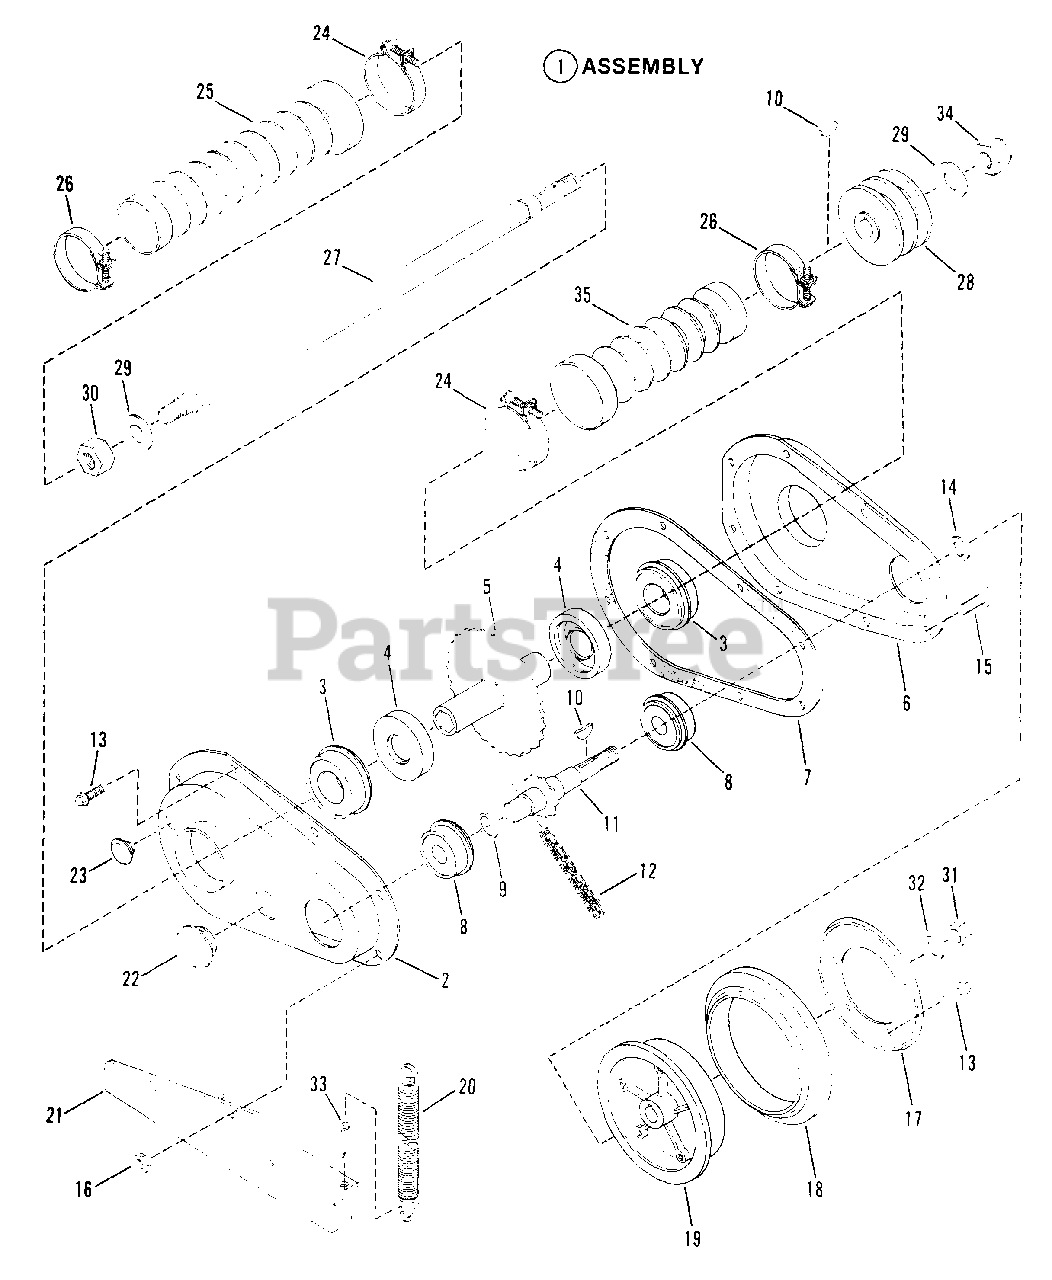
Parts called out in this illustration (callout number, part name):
1	ASSEMBLY, Chain Case
2	COVER, Chain Case, R.H.
3	BEARING, 3/4"
5	HUB & SPROCKET
6	COVER, Chain Case, L.H.
7	GASKET, Chain Case
8	BEARING
9	O-RING, 15/32
10	KEY, Woodruff, 3/32 x 1-1/2"
11	DRIVE SPROCKET
12	CHAIN
13	SCREW, #10-24 x 1/2" Hex Washer Self-Tap (Torx)
14	WASHER, 5/16"
15	SCREW, 1/4-28 x 1/2", Hex Head Cap
16	NUT, 1/4-28 Hex Lock
17	PLATE
18	RING, Rubber
19	HUB, Rubber Ring
20	SPRING
21	BRACKET, Shift
22	PLUG, 3/4"
23	PLUG, 3/8"
24	CLAMP, 1-7/8"
25	COVER, Shaft
26	CLAMP, 1-1/2"
27	SHAFT, Hex
28	PULLEY, V-Belt
29	WASHER, 7/16 SAE
30	NUT, 7/16-20 Hex Center Lock
31	NUT, 3/8-24 Hex Lock
32	WASHER, 3/8 Belleville
33	COTTER-PIN, 5/32" x 1"
34	JAM-NUT, 7/16-20 Hex Ctr. Lock
35	COVER, Shaft
